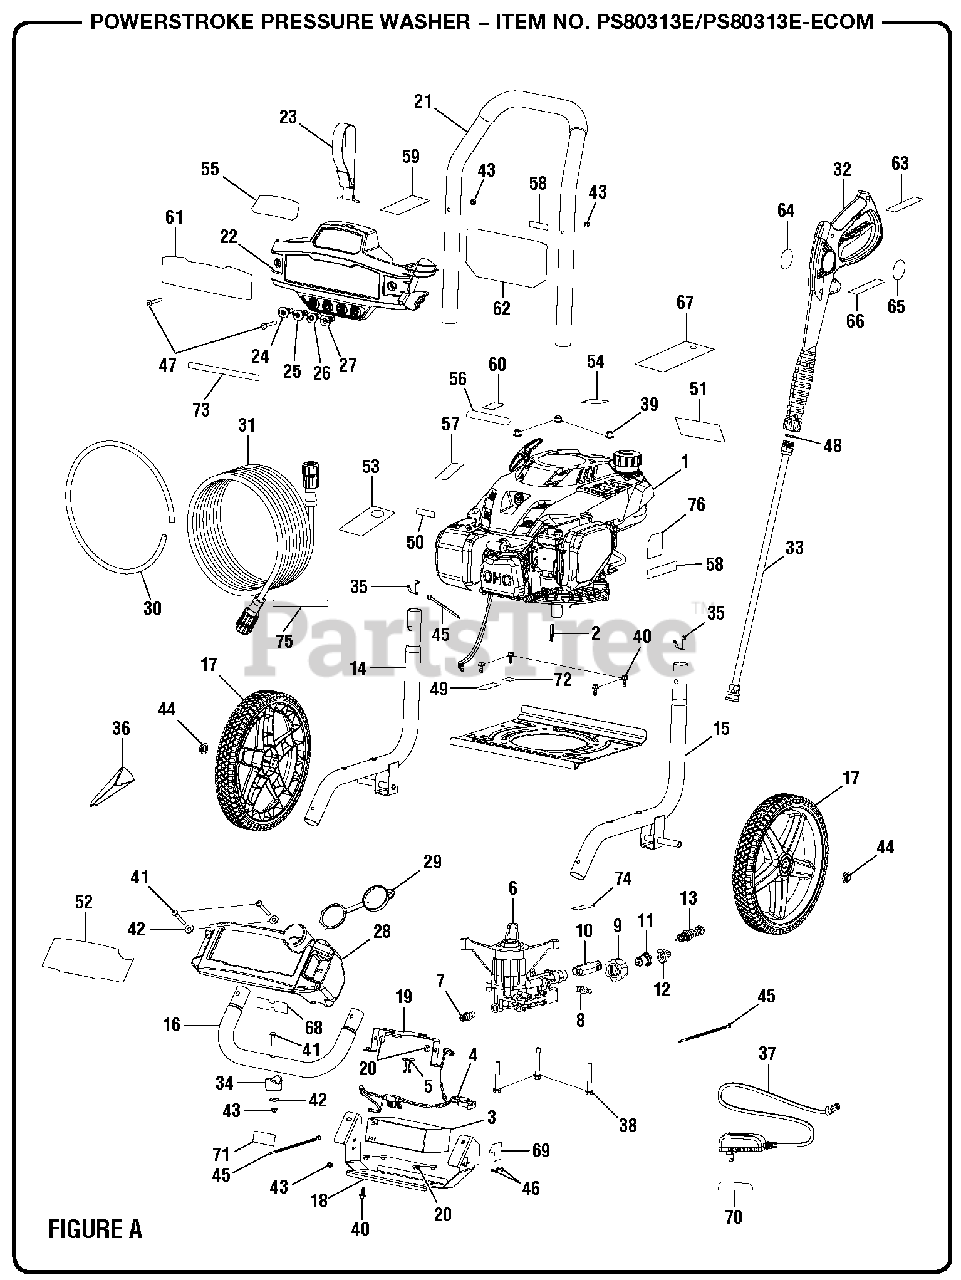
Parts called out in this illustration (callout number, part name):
2	Output Shaft Key
3	Battery
4	Battery and Charger Wire Harness
5	Adhesive Backed Cable Twist Tie
6	Pump
7	Thermal Release Valve
8	Soap Injector Kit
9	Inlet Filter Adapter
10	Outlet Tube
11	Inlet Filter Connector
12	Inlet Filter Screen
13	Unloader Valve Assembly
14	Left Frame Assembly
15	Right Frame Assembly
16	Front Frame Assembly
18	Battery Mount Bracket
19	Battery Hold Down
21	Handle Assembly
22	Hose & Nozzle Holder Assembly
23	Hose Holder Strap
24	0deg Deg Nozzle
25	25deg Deg Nozzle
26	40deg Deg Nozzle
27	Soap Nozzle
28	Soap Tank
29	Soap Tank Cap
30	Chemical Siphon Tube
31	Hose (30 ft.)
32	Trigger Handle Assembly
33	Wand Assembly
35	Handle Spring Clip
37	Battery Charger
38	Bolt (M8 x 60 mm, Flange Hex Hd.)
39	Flange Lock Nut (M8)
40	Flange Bolt (M6 x 16 mm)
41	Screw (M6 x 48 mm, T-30 Torx Hd.)
42	Washer (1/4 in.)
43	Lock Nut (M6)
44	Wheel Cap
46	Screw (M4 x 12 mm, T-20 Torx Hd.)
47	Bolt (M6 x 42 mm, T-30 Torx Pan Hd.)
49	Combustion Warning Label
50	Choke Label
51	Danger Label
52	Detergent Tank Label
53	Oil Dipstick Hang Tag
54	E85 Label
55	Electric Start Label
56	Subaru Label
57	Hot Surface Label
58	Inquiries Label
59	Standard Nozzle Hangtag
61	Performance Label
62	Quick Start Label
63	Trigger Handle Warning Label (Fr/Sp)
64	Trigger Wand Logo Label
65	Trigger Handle Warning Label (En)
66	Trigger Handle Spec Label
67	Danger Hang Tag
68	Battery Cordwrap Label
69	Battery Bracket Label
70	Battery Maintainer Label
71	Battery Replacement Label
72	Add Oil Label
73	Nozzle Selection Label
74	Hose Outlet Label
75	Hose Hangtag
76	Fuel Valve Label
